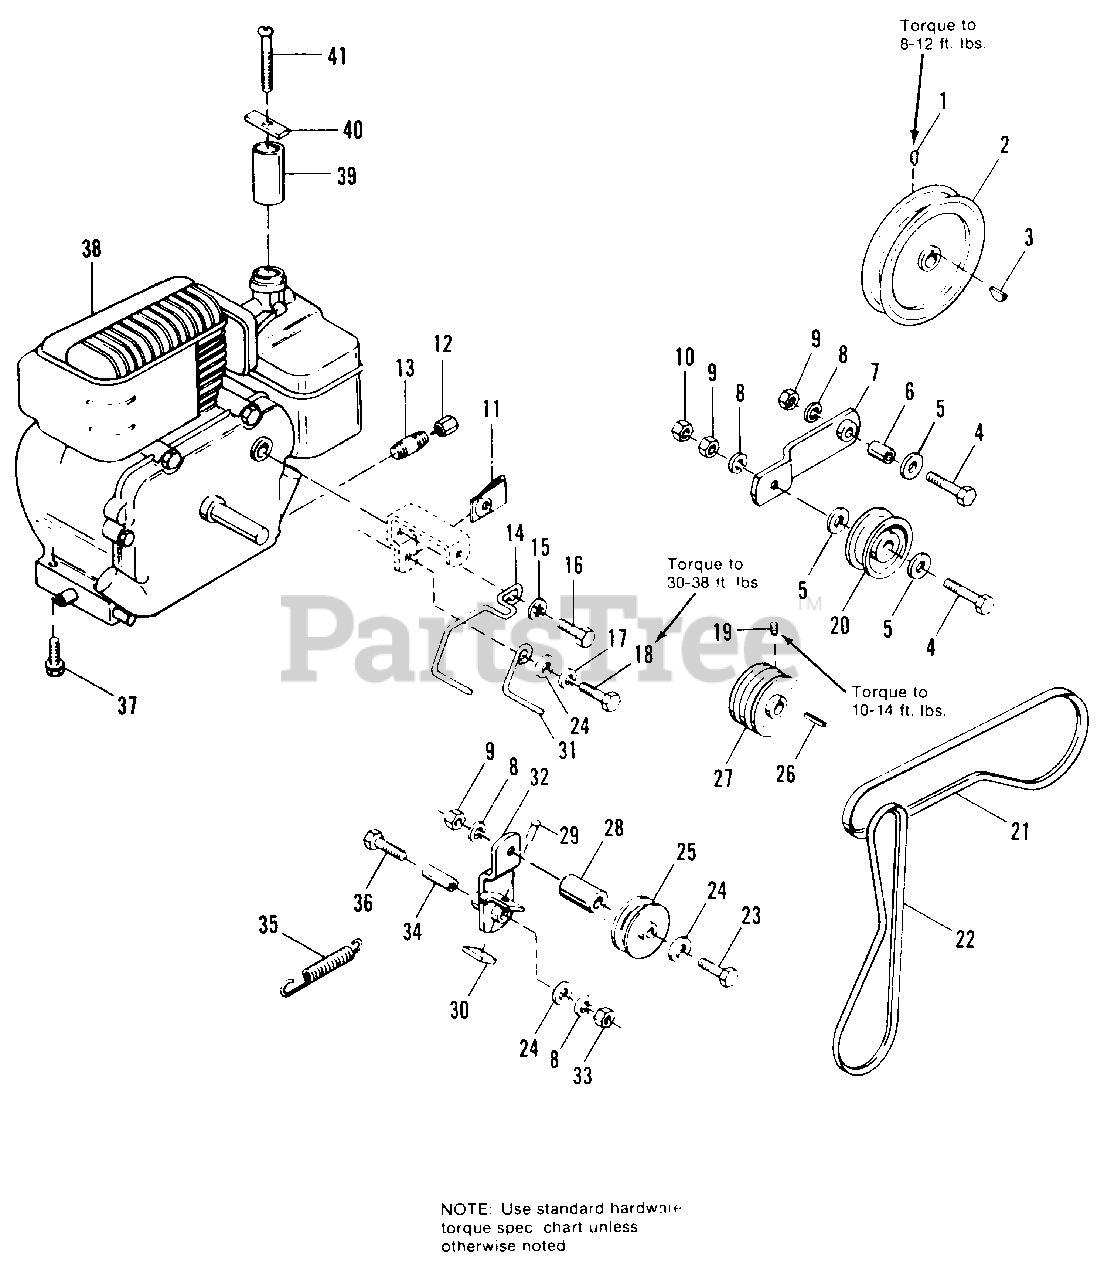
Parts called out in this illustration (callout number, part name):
1	SETSCREW, 5/16-18 x 5/16
3	KEY Woodruff, #9, 3/16 x 3/4
4	CAPSCREW, Hex Hd, 3/8-16 x 2-3/4
5	WASHER, Plain, 3/8
6	RACE, Inner Bearing
7	LEVER ASSY., Idler
8	LOCKWASHER 3/8
9	NUT, Hex Full 3/8-16
10	LOCKNUT, Hex, 3/8-16
11	NUT, Retainer 5/16-18
12	CAP, Pipe (1690305 Only)
13	NIPPLE, Pipe (1690305 Only)
14	STOP, Belt
15	LOCKWASHER Int., 1/2
16	CAPSCREW, Hex Hd., 1/2-20 x 1
17	LOCKWASHER, 5/16
18	CAPSCREW Hex Hd., 5/16-18 x 7/8
19	SETSCREW, 5/16-18 x 3/8
20	PULLEY Idler
21	V-Belt (Transmission Drive)
22	V-Belt (Auger Drive)
23	CAPSCREW, Hex Hd., 3/8-16 x 1-1/2
24	WASHER, Plain, 5/16
25	PULLEY, Idler
26	KEY
27	PULLEY, Engine
29	RIVET, #7 x 3/8
30	PAD, Brake
32	LEVER & BRAKE ASSY.
33	LOCKNUT, Jam, 3/8-16
36	CAPSCREW, Hex Hd., 3/8-16 x 2-1/4
37	SCREW, Hex, Washer Hd,. Taptite, 3/8-16 x 1-1/4
39	TUBE (1690305 Only)
40	CLAMP (1690305 Only)
41	SCREW, Machine #10-32 x 3
